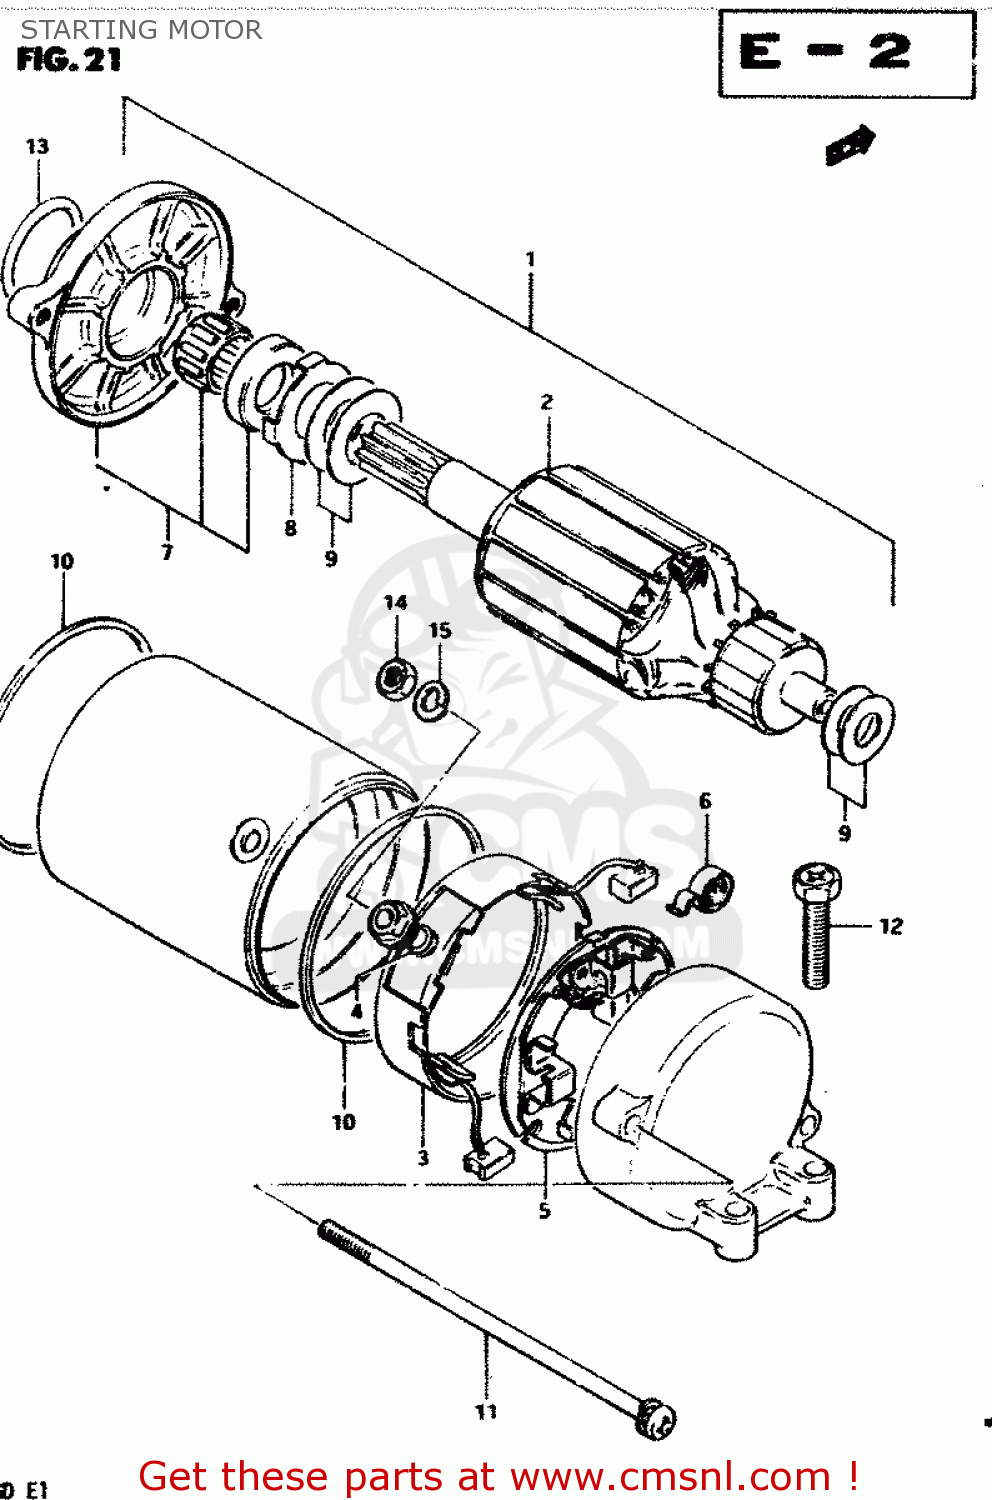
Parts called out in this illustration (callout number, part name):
1	MOTOR ASSEMBLY,STARTING
2	ARMATURE
3	BRUSH TERMINAL SET (+)
4	O RING
5	HOLDER,BRUSH
6	SPRING,BRUSH
7	HOUSING SET,STARTING MOTOR
8	SHIM SET
9	SHIM SET
10	SEAL,RING
11	BOLT,STARTING MOTOR HOUSING
12	SCREW (6X25)
13	O RING(D:2,ID:24.5)
14	NUT 6MM
15	LOCK WASHER
